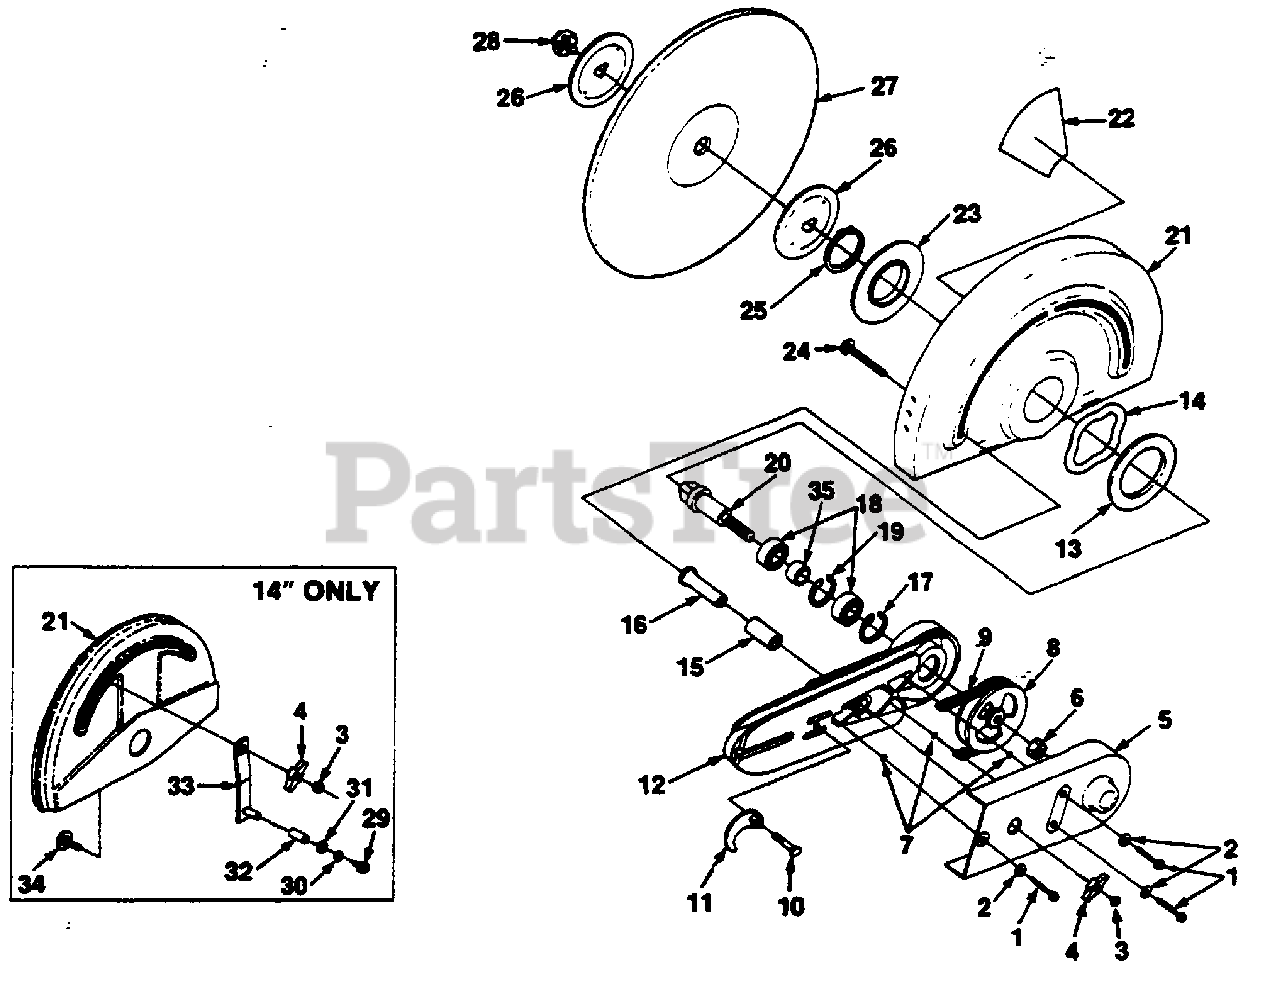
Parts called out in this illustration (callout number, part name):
1	SCREW- Slotted (1/4-20 x 1 1/2")
2	WASHER- Flat (1/4")
3	NUT
5	COVER- Arm
6	NUT- Hex lock (1/2-13)
7	"O" RING
8	PULLEY- Driven
9	BELT- "V" drive
10	SCREW- Hex hd. (5/16-18 x 11/2")
11	CAM & ADJUSTER
12	ARM- Wheel
14	SPRING- Wave
15	TUBING- Rubber (12" only)
16	SPACER- Guard adjusting (12" only)
17	RING- Retaining
18	BEARING- Ball
19	RING- Retaining
20	SHAFT- Wheel
21	GUARD- Wheel (12" only)
22	LABEL- Caution
23	WASHER- Mounting (12" only)
24	BOLT- Step (5/16-18 x 31/2") (12" Only)
26	FLANGE- Wheel
27	WHEEL- Resinoid (12" only)
28	KIT- Screw, Washer, & Retaining
29	SCREW- Hex cap (1/4-20 x 5/8") (14" Only)
30	WASHER- Lock (1/4") (14" only)
31	WASHER- Flat (5/16") (14" only)
32	TUBING- Rubber (14" only)
33	ARM- Adjusting (14" only)
34	SCREW- Adjusting (14" only)
35	SPACER- Bearing
